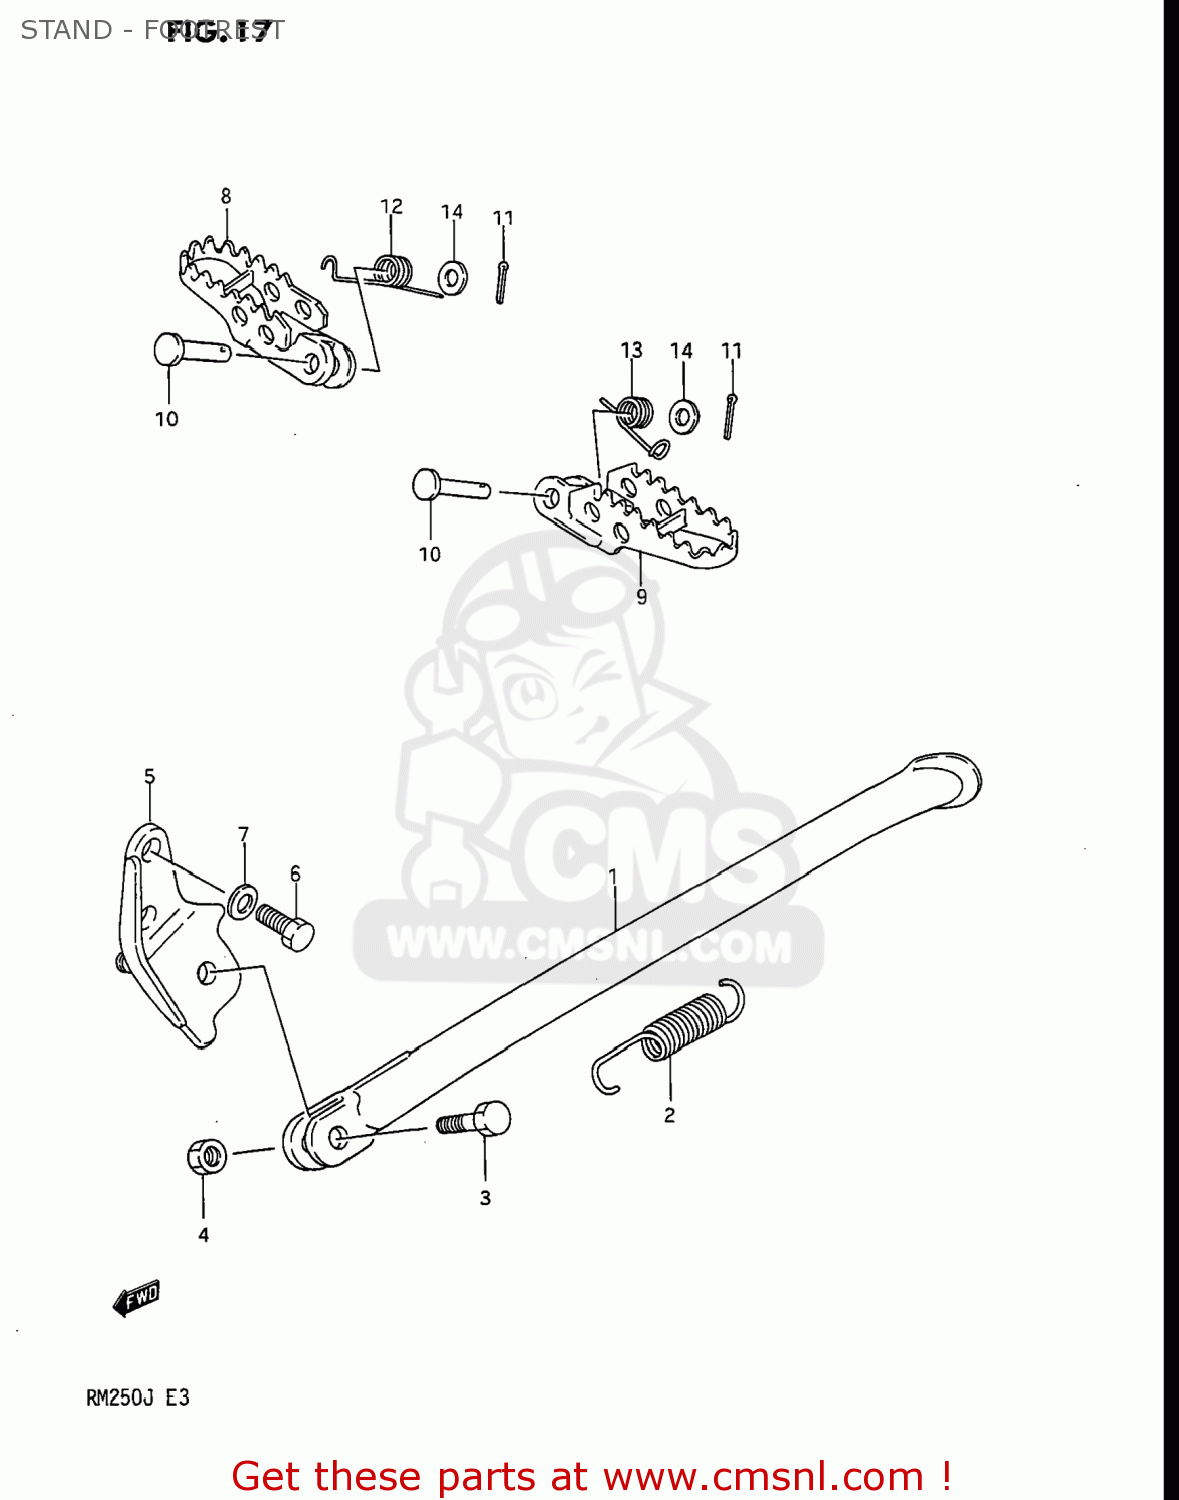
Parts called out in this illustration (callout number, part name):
1	STAND,SIDE
2	SPRING
3	BOLT(10X30)
4	NUT
5	BRACKET,SIDE STAND
6	BOLT(10X19)
7	WASHER,LOCK,10
8	FOOTREST,FRONT,RIGHT
9	FOOTREST,FRONT,LEFT
10	PIN
11	PIN 25X20
12	SPRING
13	SPRING
14	WASHER
